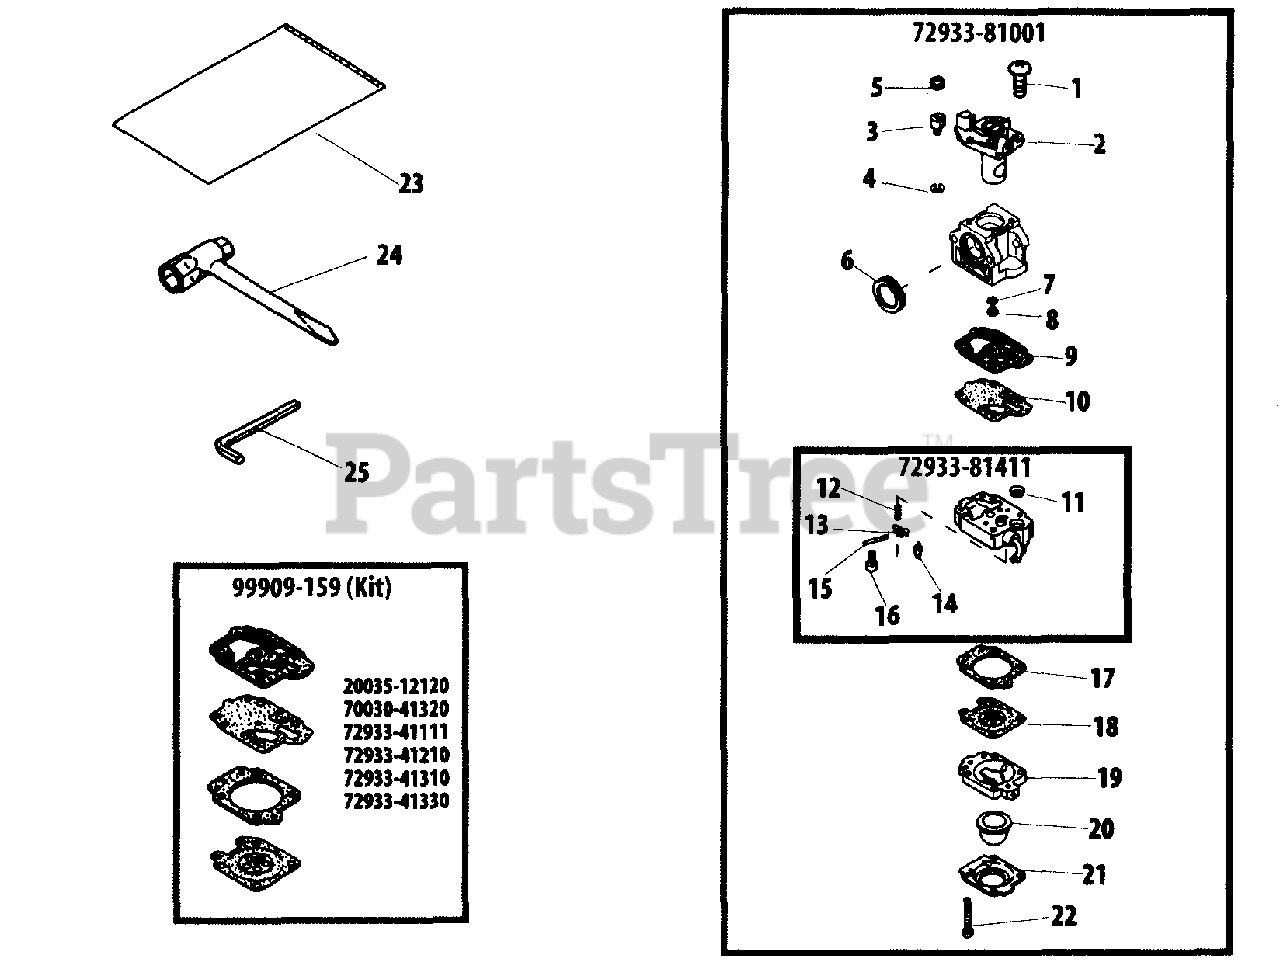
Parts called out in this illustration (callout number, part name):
1	SCREW, THROTTLE COLLAR
2	VALVE ASSY, THROTTLE
3	SWIVEL
4	E-RING
5	CLIP
6	RING, PACKING
7	O-RING
8	JET, MAIN - #43
9	GASKET, PUMP
10	DIAPHRAGM, PUMP
10	BODY ASSY, PUMP
11	SCREEN, FUEL INLET
12	SPRING, METERING LEVER
13	LEVER, METERING
14	VALVE, INLET NEEDLE
15	PIN, METERING LEVER
16	SCREW
17	GASKET, METERING DIAPHRAGM
18	DIAPHRAGM, METERING
19	BODY ASSY, PURGE
20	BULB, PURGE
21	RETAINER, PURGE BULB
22	SCREW
23	BAG, TOOL
24	T-WRENCH 13×19 MM
25	WRENCH, ALLEN 4 MM
